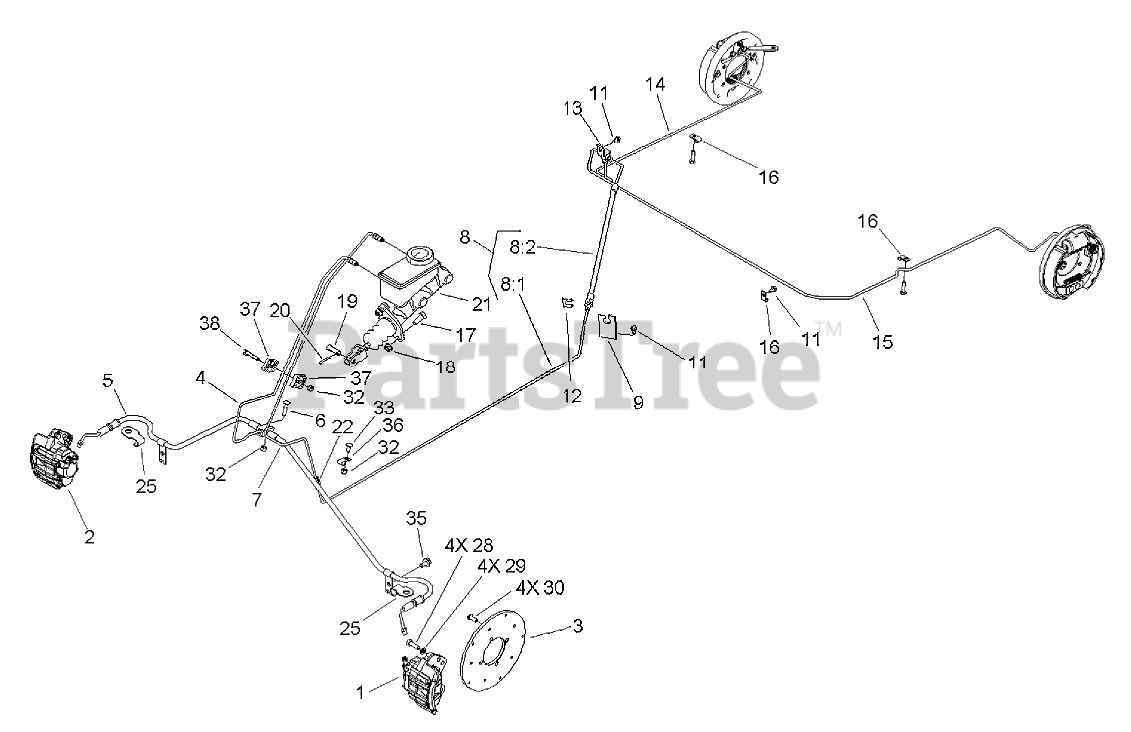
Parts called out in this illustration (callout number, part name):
1	CALIPER-LH
2	CALIPER-RH
4	TUBE-BRAKE, FRONT
5	Hose ASM-Frt
6	SCREW-CARR
7	TUBE-BRAKE, REAR
8	Complete Rear Brake Hose ASM
8:1	TUBE-BRAKE, REAR
8:2	HOSE-BRAKE, REAR
9	BRACKET-HOSE, BRAKE
11	SCREW
14	TUBE-BRAKE, REAR (RH)
15	TUBE-BRAKE REAR, LH
16	CLIP-CLOSED, INSULATED
17	SCREW-HH
18	NUT-HHF, WHIZ
19	PIN-CLEVIS
20	PIN-COTTER
21	MASTER CYLINDER ASM
22	UNION
25	BRACKET-HOSE
28	SCREW-HH
29	WASHER-LOCK
30	SCREW-HSBH
32	NUT-LOCK, NI
33	SCREW-CARR
35	SCREW-HWHTF
36	CLAMP-R
37	CLAMP-TUBE
38	SCREW-HH
